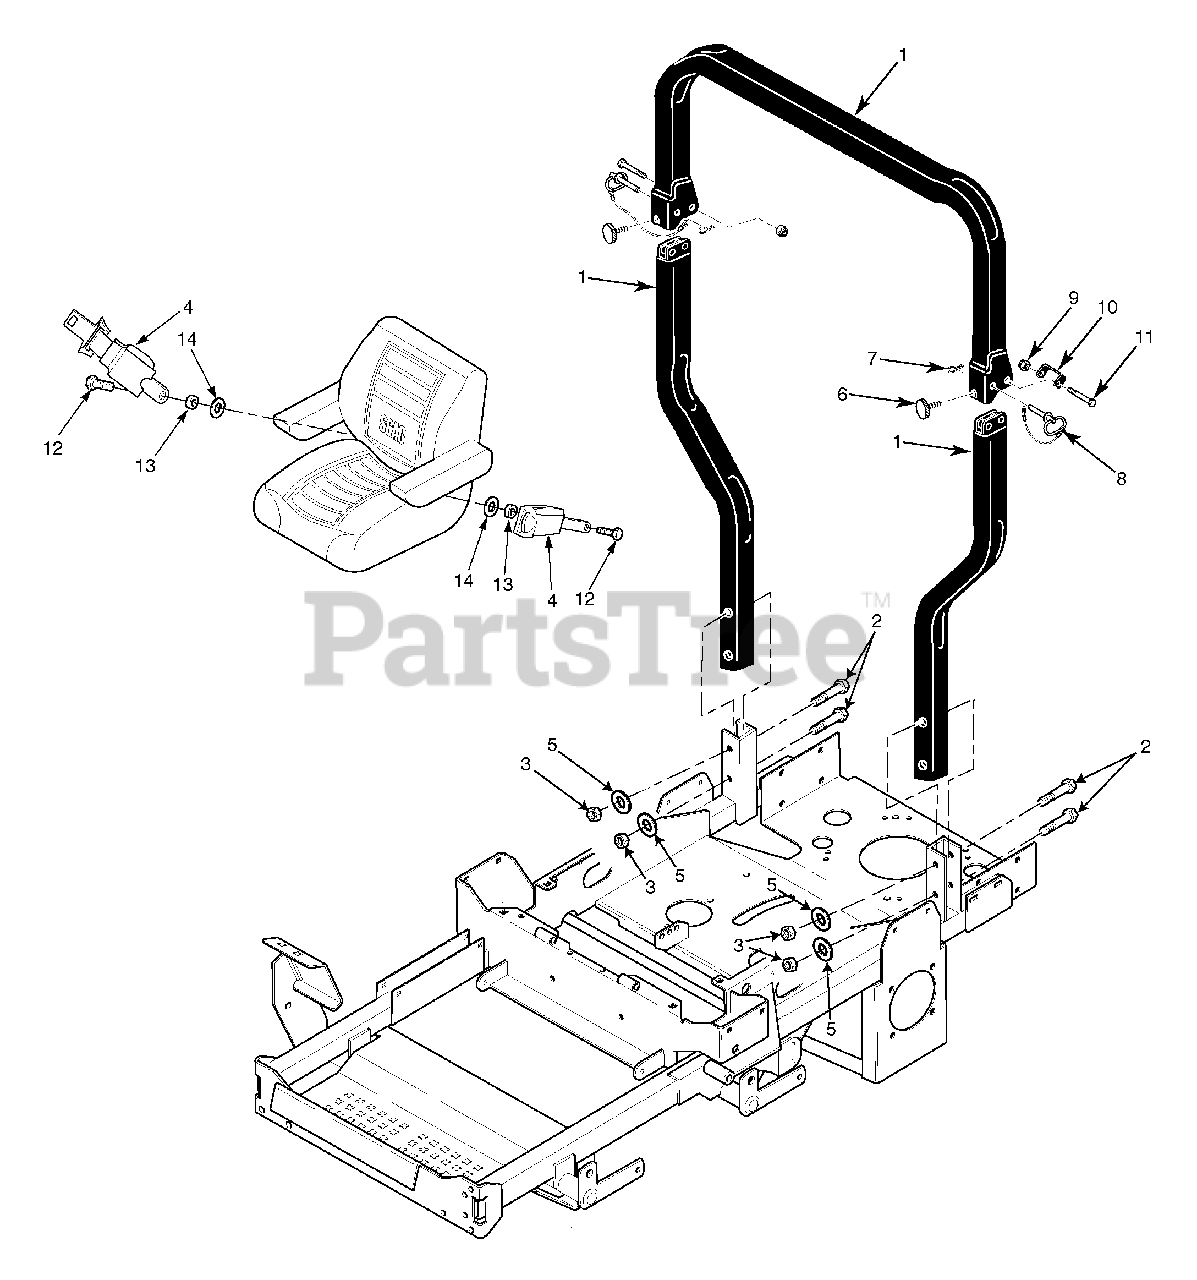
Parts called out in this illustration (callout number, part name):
1	STC Foldable ROPS
2	Bolt, Hex Head 1/2-13 x 3-1/2"
3	Nut, Center Lock 1/2-13
4	Retractable Seat Belt
5	Flatwasher, 1/2-.562 x 1.375 x .109
6	Thumb Screw, 5/16-18 NC x 3-4"
7	Hair Pin, Cotter
8	Pin
9	Nut, Center Lock 1/2-13
10	Bracket, Stop
11	Bolt, Hex Head 1/2-13 x 3-1/2"
12	Bolt, Hex Head 7/16-20 x 1"
13	Spacer
14	Flatwasher, 7/16-.500 x 1.25 x .083
